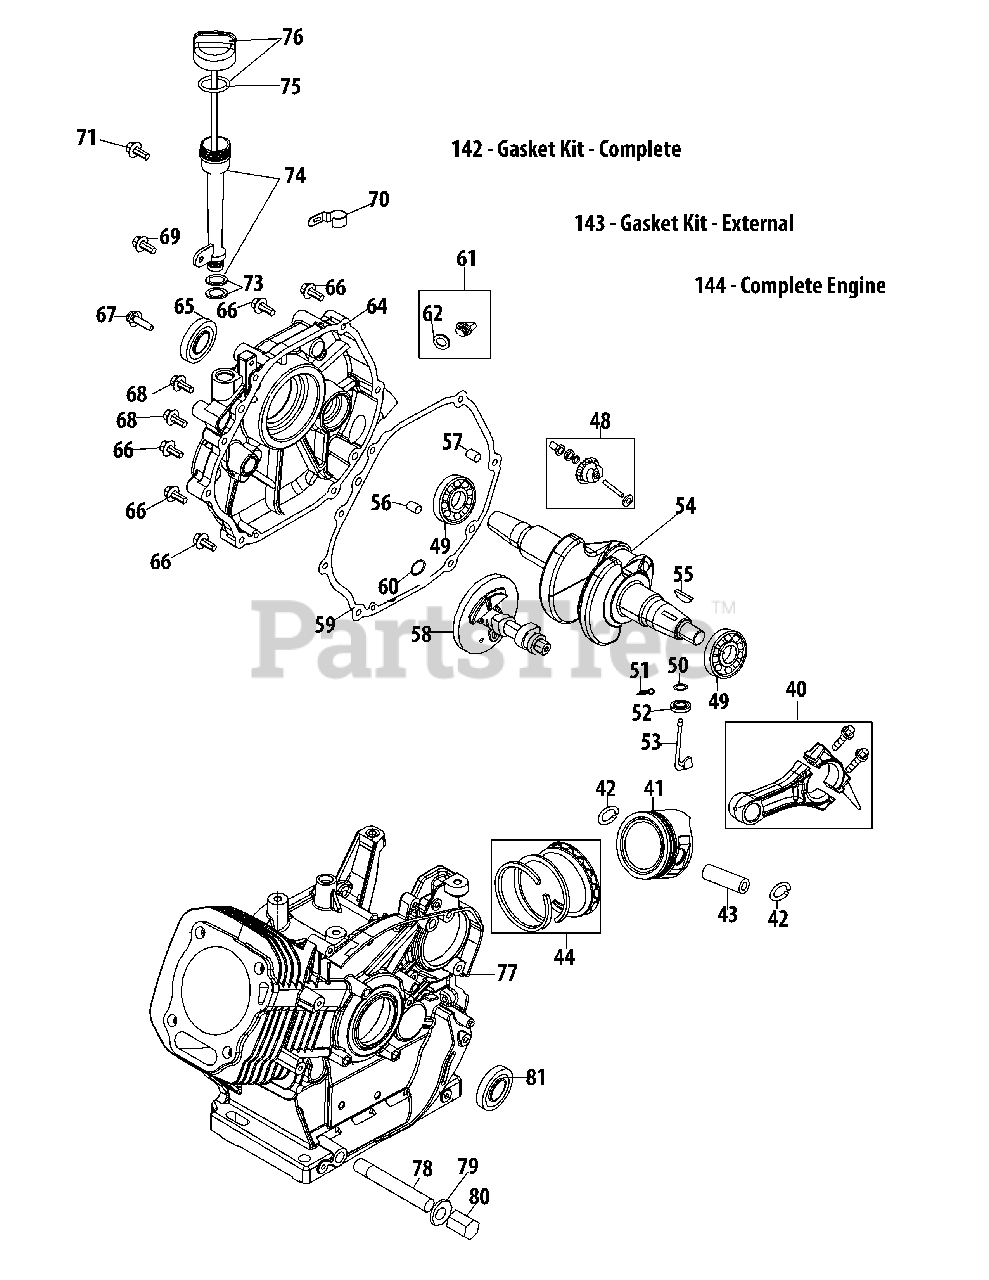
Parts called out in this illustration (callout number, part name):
40	Connecting Rod Assembly
42	Piston Pin Snap Ring
43	Piston Pin
44	Piston Ring Set
48	Governor Gear/Shaft Assembly
49	Radial Ball Bearing
50	Washer 8×20×0.8
51	Cotter Pin
52	Governor Seal
53	Governor Arm Shaft
54	Crankshaft Kit
55	Woodruff Key
56	Dowel Pin 9×12
57	Dowel Pin 7×14
58	Camshaft Assembly
59	Crankcase Cover Gasket
60	Washer 16×24×0.5
61	Oil Fill Plug Assembly
64	Crankcase Cover
64	Crankcase Cover Kit
65	Oil Seal, 30×46×8
66	Bolt M8×38
67	Bolt M8×45
68	Bolt M8×35
69	Bolt M6×16
70	Dipstick Clamp
71	Bolt M6×8
73	Oil Fill Tube O-Ring
74	Oil Fill Tube Assembly
75	Dipstick O-Ring
76	Dipstick Assembly
77	Crankcase Kit
77	Short Block Assembly
78	Oil Drain Pipe
79	Washer 10×16×1.5
80	Oil Drain Plug
80	Oil Drain Assembly
81	Oil Seal 30×46×8
142	Gasket Kit - Complete
143	Gasket Kit - External
144	Complete Engine
